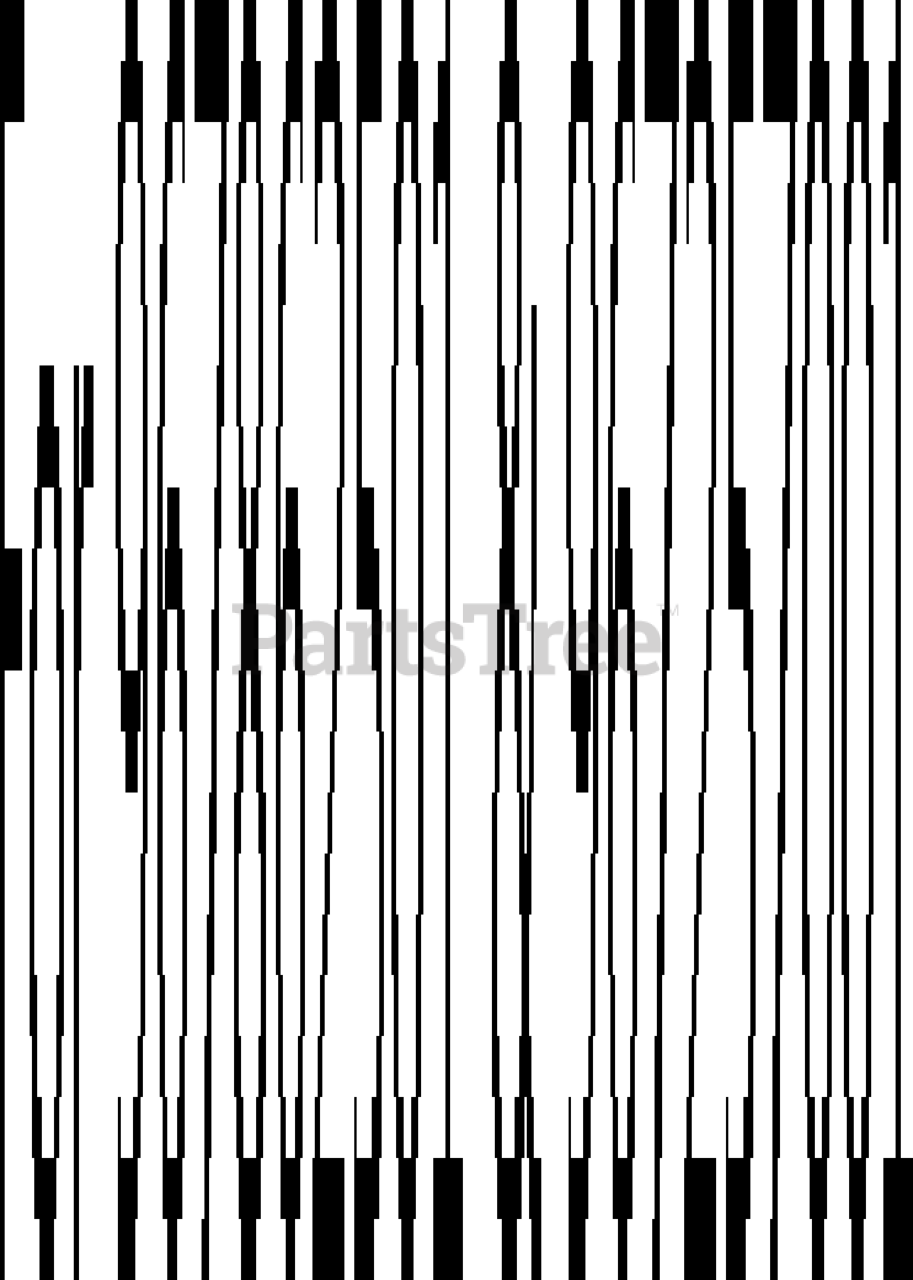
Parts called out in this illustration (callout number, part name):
1	NUT M53S / M48S
3	WHEEL PRO HUSQVARNA
4	BALL BEARING 6201-2RS/C3 W10
5	WHEEL ASSY PRO HUSQVARNA
6	SPACER PRO
7	LOCKING NUT FLANGE
8	SPACER M53 L=14
9	SPACER WASHER M53S / M48S
10	SHIELD PRO
13	RING M53S / M48S
14	RETAINING RING
17	SPRING M53 / M48
18	BALL M53 / M48
21	LEVER ASSY M53 / M48 M53
23	SPRING M53 / M48
24	FLANGE NUT
25	BOLT FLANGE M6X16
28	AXLE ASSY M53 PRO
33	SPRING M53 / M48
35	PINION PRO
44	SCREW RXS B8X9.5
46	BRACKET M53 / M48
47	SPRING M53S / M48S
48	SCREW ITXPANTT M5X10 ZPB (A00
49	CUP PRO
52	WHEEL PRO, DRIVING HUSQVARNA
53	WHEEL ASSY PRO, DRIVING HUSQVA
